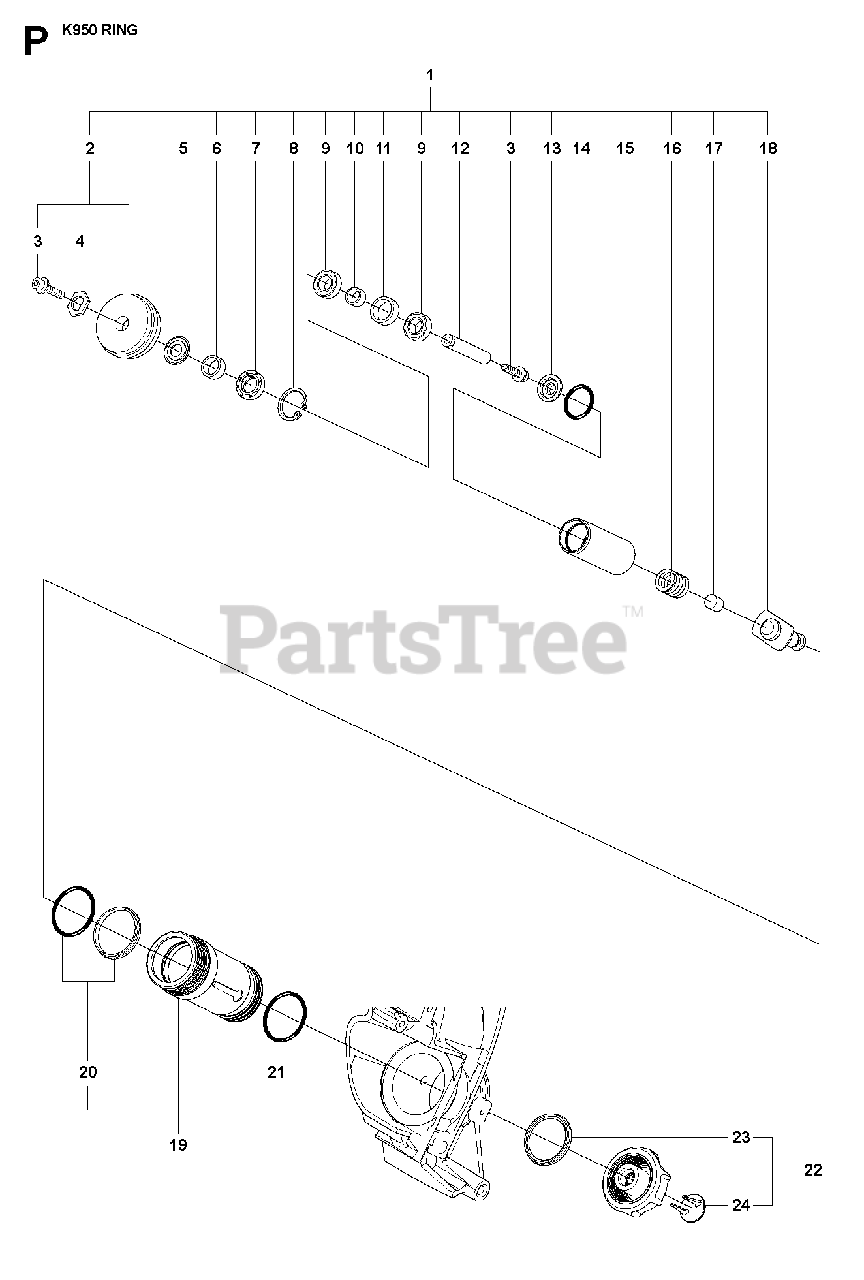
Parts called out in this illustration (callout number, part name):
1	BEARINGIncl. 2, 3, 5 - 18
2	GUIDE ROLLERIncl. 3, 4
9	BALL BEARING
19	SLEEVEIncl. 20, 21
